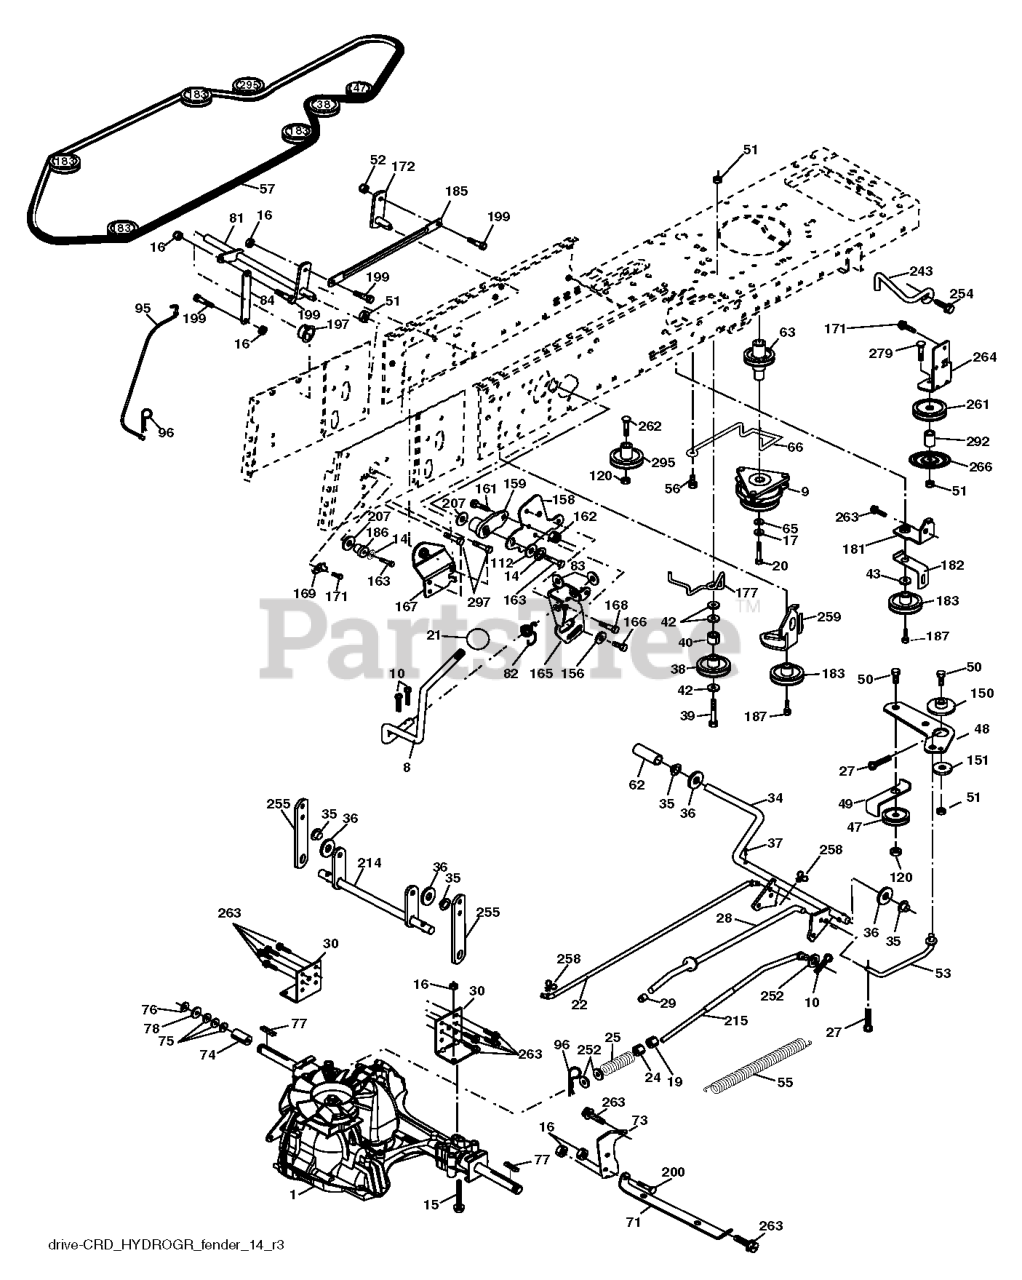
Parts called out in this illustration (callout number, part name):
8	ROD SHIFT FENDER ADJUST LT
9	CLUTCH.ELECTRIC.OGURA.EURO.
10	PIN COTTER
14	LOCKWASHER
15	BOLT HEX 5/16-18 GR 5
16	NUT.71038.31-18.HEX.NYLOCK
19	NUT
20	BOLT HEX 7/16-20X4-1/4"
21	KNOB.DUCKHEAD.1/2
22	ROD
24	NUT
25	SPRING BRAKE ROD
27	COTTER PIN
28	ROD, PARKING BRAKE
29	CAP
30	BRKT, TRNSXLE MNT 20"
34	SHAFT, FOOT PEDAL
35	BEARING.NYLON
36	WASHER LT
37	DRIVE PIN
38	PULLEY.FLAT
42	WASHER
43	WASHER T
47	IDLER PULLEY
48	BELLCRANK, CLUTCH
49	RETAIN BELT
50	BOLT.3/8-16X1.50
52	LOCKNUT
53	LINK.CLUTCH.7.66.2005
55	SPRING, RETURN LT
56	SCREW.3/8-16
57	V-BELT 113"
62	PEDAL COVER T
63	PULLEY.ENGINE.CVX.LT
65	LOCKWASHER
66	KEEPER BELT ENGINE
71	STRAP TORQUE LH HYDRO
73	STRAP TORQUE RH HYDRO
74	SPACER AXLE
77	SQUARE KEY
81	ASM.CROSS.SHAFT.REAR.CRD.0510
82	SHIFT SPRING
83	WASHER
84	LINK.PNT.TRANSAXLE.0510.CRD
95	LINK
96	RETAINER M
112	WASHER LT
120	NUT LOCK FLG 3/8-16 UNC
150	BUSHING.BELLCRANK.GRD.DR
151	WASHER 12/32X2X10GA
156	WASHER.SRRTD.5/16
158	BRACKET
159	RB HUB.SHIFT
161	BOLT
162	NUT.CROWNLOCK.1/4
163	BOLT
165	RP BRACKET
166	CAPSCREW.HXHD.FLG.5/16-18X.625
167	BRACKET.SUPT.SHIFT.CRD
168	BOLT.SHOULDER.5/16-18X
169	PLATE.FASTENING.CROSS.SHAFT
171	SCREW LT
172	LINK
181	BRACKET
182	BELT GUIDE
183	PULLEY.V-IDLER.
185	LINK
186	HUB.TAPERED.ROUND.CRD
187	BOLT.5/16-18X1.25
197	NYLINER SNAP 5/8" ID
199	BOLT SHOULDER 5/16-18 UNC
200	BOLT
207	WASHER NYL
214	LEVER
215	ROD
243	BRACKET, ANTI-ROTATION
252	WASHER
254	SCREW 3/8-16X1
255	SHAFT
258	CLIP RETAINER
259	BRACKET
261	FLAT IDLER PULLEY
263	SCREW, 3/8-16X3/4
266	PROTECTOR
279	BOLT
292	SPACER
295	PULLEY IDLER COMPOSITE
297	SCREW LT.3/8-46X5/8
